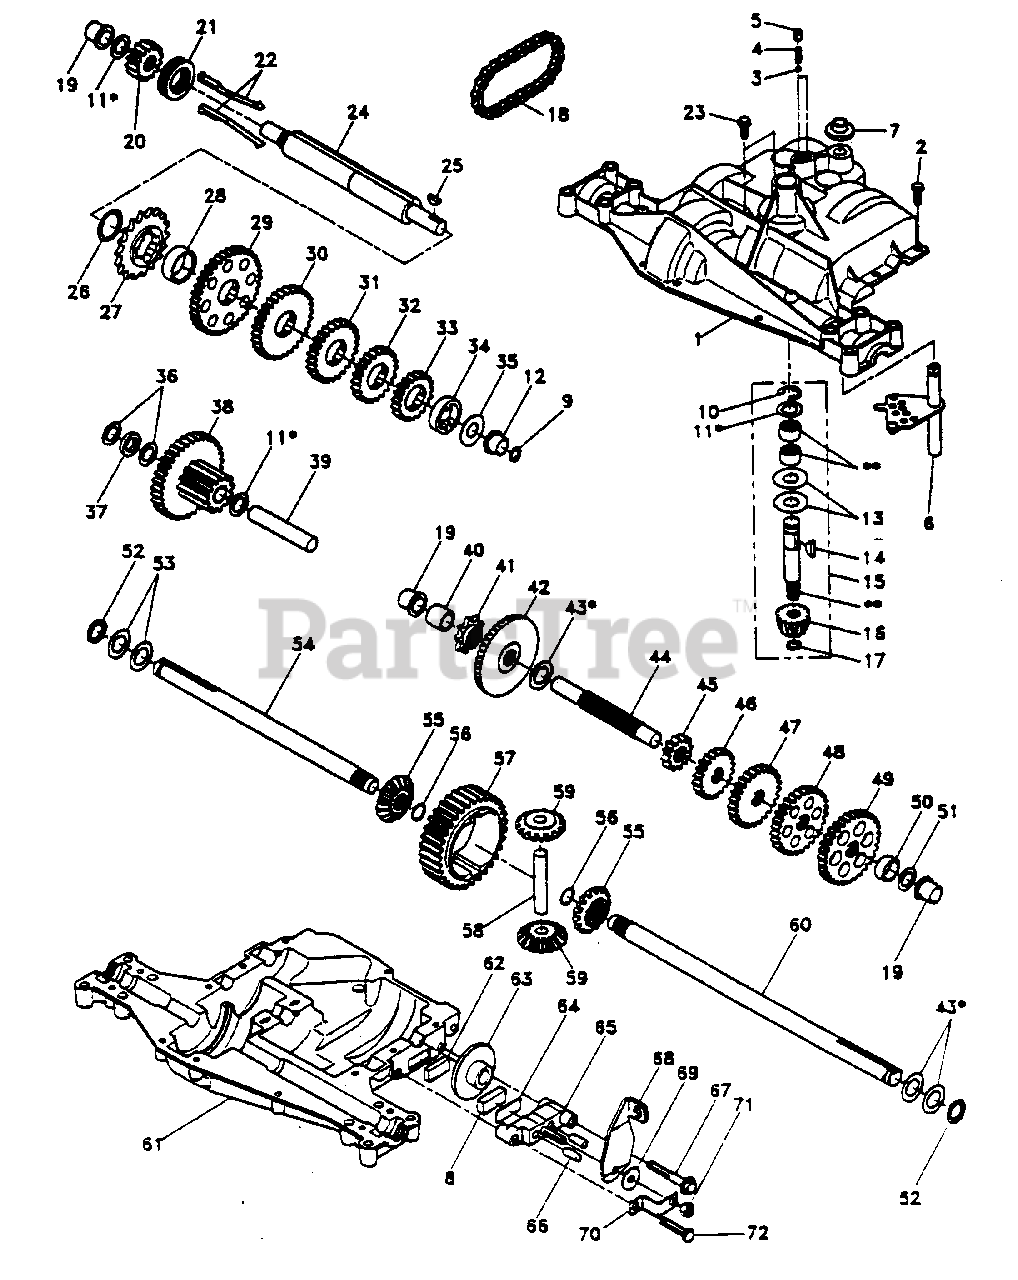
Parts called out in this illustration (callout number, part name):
1	Housing, Upper
2	Screw, Self-Tapping, Large 1/4-20 x .734
3	Ball, Detent
4	Spring, Detent
6	Kit, Shifter Assembly
7	Boot, Shifter
8	Puck, Friction
9	Seal, Oil
10	Ring, Retaining
11	Assembly, Kit, Shim .625 Shaft
12	Bearing, Flange
13	Washer, Plain .632 x 1.38 x .046
14	Key, Woodruff, #9
15	Assembly, Kit, Input Shaft
16	Pinion, Bevel, 14 Teeth
17	Ring, Retaining
18	Chain, 24 Pitches
19	Bearing, Flange
20	Gear, Spur, 14 Teeth
21	Collar, Clutch
22	Assembly, Kit, Clutch Keys
23	Screw, Self-Tapping, with Sealer
24	Shaft, Intermediate
25	Key, Woodruff, #61
26	Ring, Retaining
27	Sprocket, 18 Teeth
29	Gear, Spur, 37 Teeth
30	Gear, Spur, 30 Teeth
31	Gear, Spur, 25 Teeth
32	Gear, Spur, 22 Teeth
33	Gear, Spur, 19 Teeth
34	Spacer 1.133 x 1.50 x .375
35	Washer, Plain .640 x 1.37 x .061
36	Washer, Plain .632 x 1.00 x .026
37	Spacer .630 x 1.00 x .169
38	Assembly, Gear, Combination of 12 Teeth and 35 Teeth
40	Spacer .635 x .875 x .755
41	Sprocket, 9 Teeth
42	Gear, Bevel, 42 Teeth
43	Assembly, Kit, Shim .750 Shaft
45	Gear, Spur, 12 Teeth
46	Gear, Spur, 20 Teeth
47	Gear, Spur, 25 Teeth
48	Gear, Spur, 28 Teeth
49	Gear, Spur, 31 Teeth
50	Spacer .781 x 1.00 x .375
51	Washer, Plain .632 x 1.00 x .060
52	Washer, Neoprene
53	Washer, Plain .758 x 1.25 x .031
54	Axle, L.H.
55	Gear, Miter, 15 Teeth
56	Ring, Retaining
57	Gear, Spur, 32 Teeth
59	Gear, Miter, 15 Teeth
61	Housing, Lower
62	Puck, Friction
65	Jaw, Brake
67	Screw, Self-Tapping, Large 5/16-18 x 2.25
68	Lever, Actuating
69	Washer, Plain .321 x 1.00 x .055
70	Bracket, Anti-Rotation
71	Locknut 5/16-24
72	Screw, Self-Tapping, Large 5/16-18 x 1.44
73	Grease
